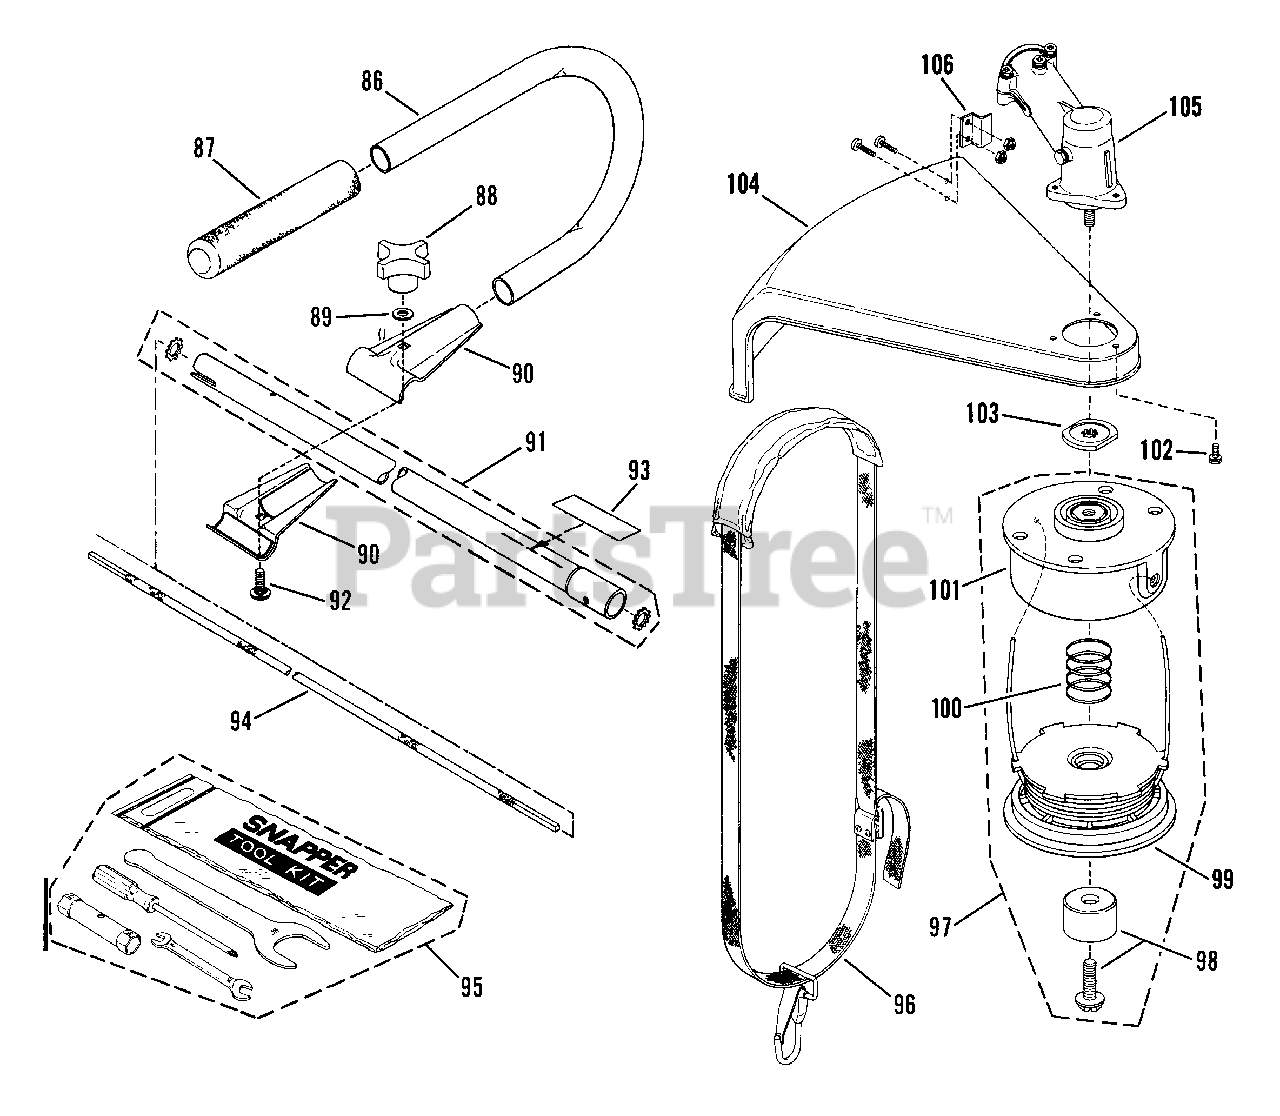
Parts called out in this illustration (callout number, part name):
86	HANDLE, "J"
87	GRIP, "J" Handle
89	WASHER
90	CLAMP, Half
91	ASSEMBLY, Liner & Tubing
92	SCREW, 5/16C x 1-3/4"
93	DECAL-WARNING
94	SHAFT, Flex (54.375" x .245", .268" Square Ends x 1")
95	TOOL KIT
96	SHOULDER STRAP
97	BUMP HEAD ASSM'Y
98	KNOB & BOLT
99	SPOOL & LINE
100	SPRING
102	BOLT, Hex Head
103	SPACER
105	GEAR HEAD
106	LINE CUTTER KIT
